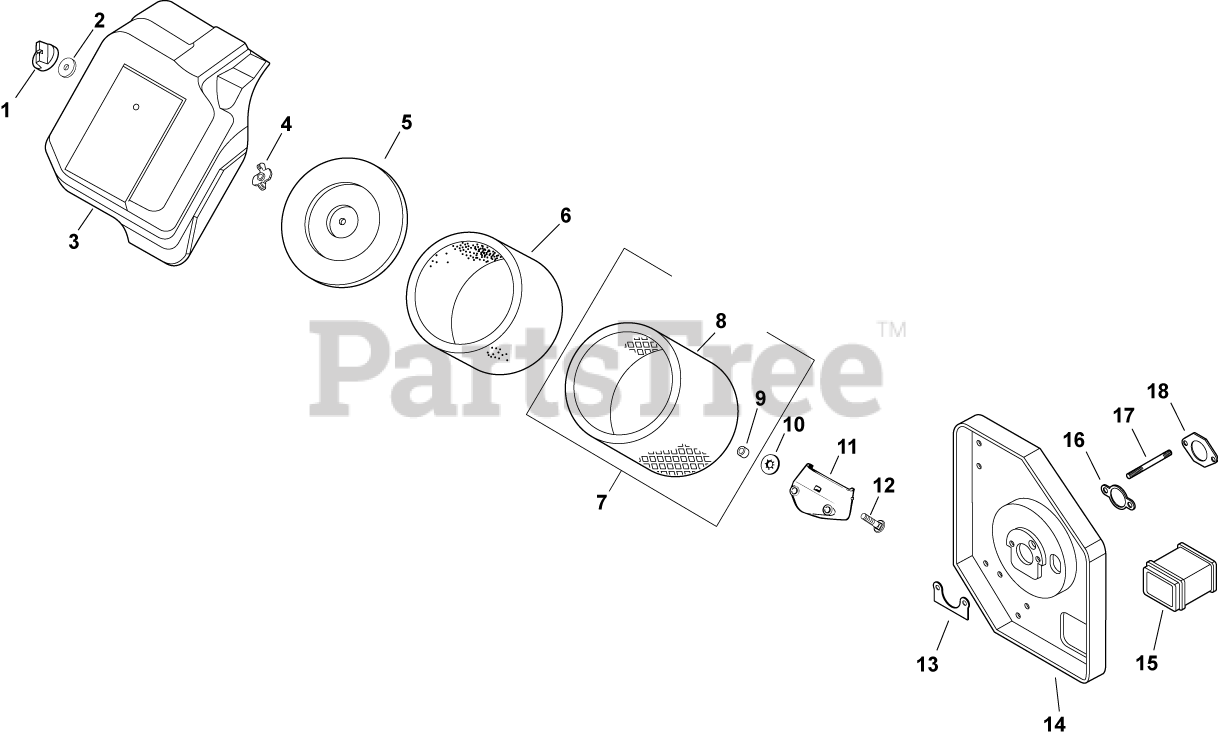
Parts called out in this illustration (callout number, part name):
1	KNOB, COVER
2	GASKET, AIR CLEANER COVER KNOB
3	COVER, AIR CLEANER BASE
4	NUT, WING
5	COVER, AIR CLEANER
6	PRE-CLEANER
7	KIT, AIR CLEANER ELEMENT
8	ELEMENT, AIR CLEANER (KM) - Also available Retail Packaged 47 883 01-S1 Air Filter Kit
9	SEAL, INNER AIR CLEANER
10	RETAINER, RING
11	CUP, FUEL SPITBACK
13	GASKET, AIR CLEANER BASE
14	BASE, AIR CLEANER
16	GASKET, AIR CLEANER BASE
1275584-S	KIT, FUEL RECOVERY
